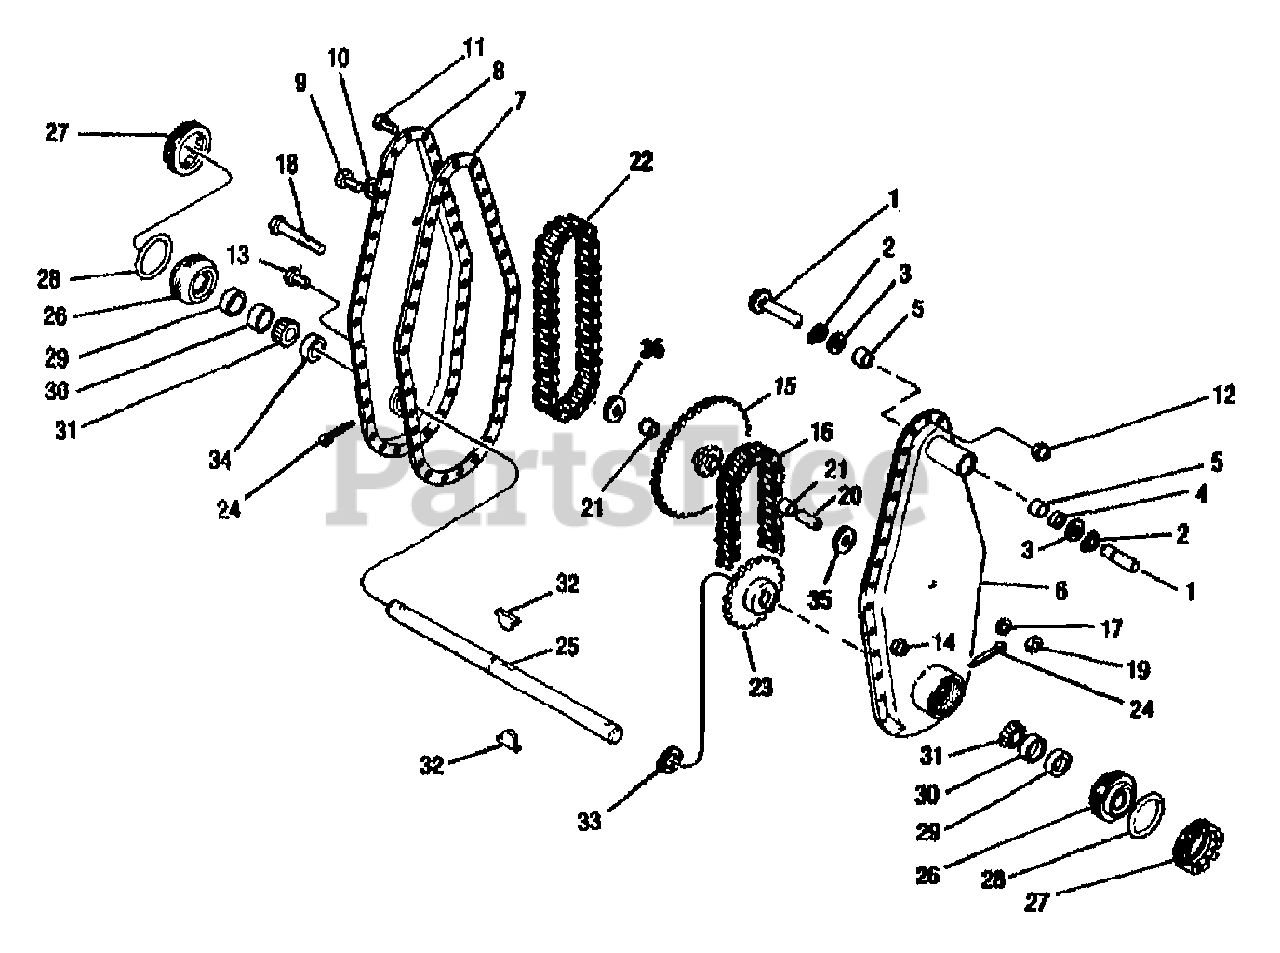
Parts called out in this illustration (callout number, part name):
1	ASSM-INPUT PTO SHAFT
2	RING-RETAIN EXT .707 ID
3	WASHER-THRUST
4	SEAL-OIL 3/4 DIAMETER
5	BEARING-NEEDLE 3/4
6	ASSM-HOUSING LH
7	GASKET-CHAIN CASE
8	ASSM-HOUSING RH
9	SCR-HH 1/2-20X.75 G5 ZP
10	WASHER-1.0X.53X.06 NYLON
11	SCR-HH 1/4-20X.625 G5 ZP
12	NUT-HT LK 1/4-20
13	SCR-HHC 5/16-18X.75 GR 5 ZP
14	NUT-TOP/LK 5/16-18 ZP
15	ASSM-SPROCKET
16	CHAIN-DRIVE ASA 50
17	WASHER-LK .375 @ DEPL
18	SCR-HH 3/8-16X2.75 G5 ZP
19	NUT-LOCK 3/8-16
20	SLEEVE-IDLER
20	BEARING-NEEDLE 1/2
22	CHAIN-DRIVE ASA 41
23	ASSM-SPROCKET 24T
24	PIN-COTTER .120X1.00 ZP
25	SHAFT-TINE
26	BEARING-CARRIER
27	RING-LOCKING
28	RING-O 3.35 ID
29	SEAL-OIL 1.25
30	BEARING-CUP
31	BRG-TAPERED ROLLER CONE
32	KEY-HI PRO .25X.875
33	RING-RET. EXT 1.25 ID
34	SPACER-1.75X1.265X.5
35	WASHER-THRUST .79X.37X.03
